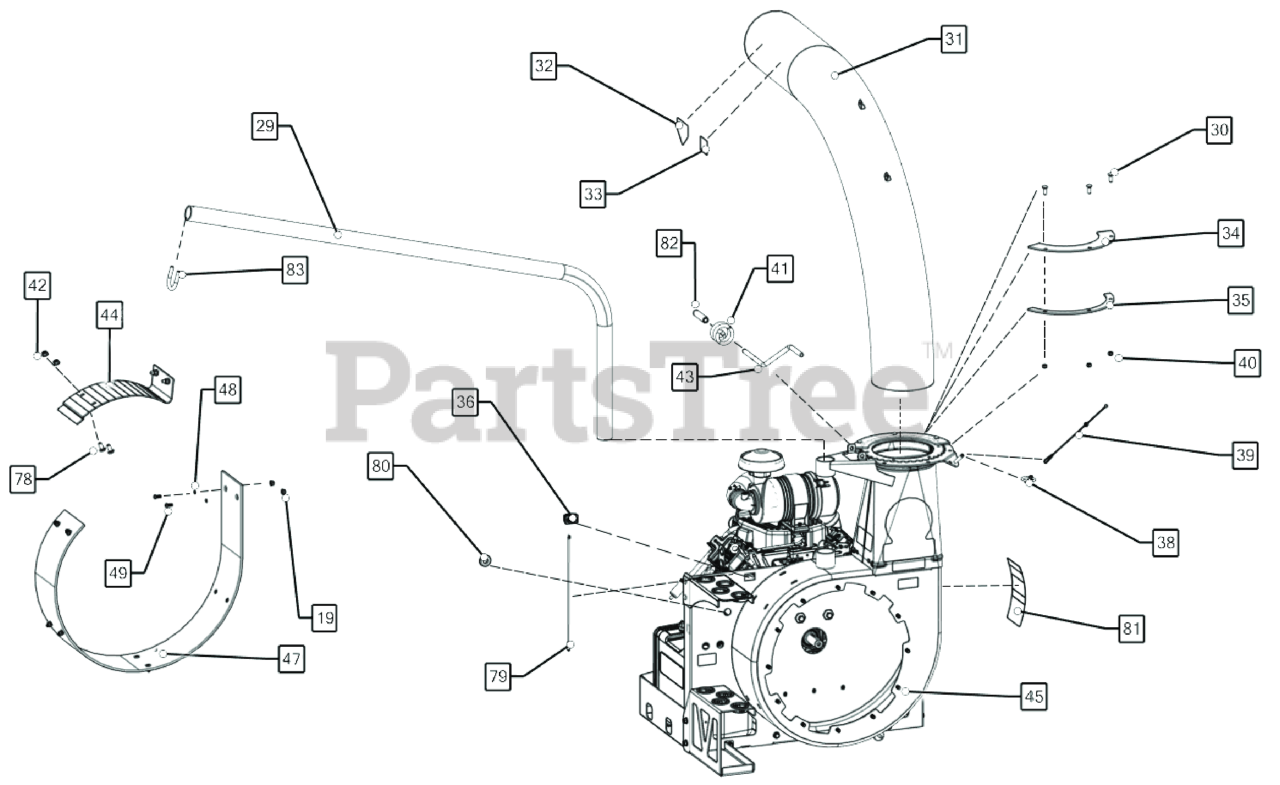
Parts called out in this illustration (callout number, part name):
19	NUT-HEX-NYLK, FLG .3125-18 ZP
29	BOOM HOSE
30	BOLT CARRIAGE 5/16"-18 X 3/4" ZP
31	ELBOW 8" DL SERVICE
32	LABEL WARNING OPEI
33	LABEL DANGER FLYING DEBRIS
34	PLATE CLAMP HALF DL
35	PLATE CLAMP SPLIT DL
36	HOURMETER, INDUCTIVE PANEL MOUNT
38	LYNCH PIN 3/16" X 1 9/16"
39	LANYARD PLASTIC 10"
40	NUT-HEX-NYLK, FLG .3125-18 ZP
41	GEAR WORM WELDED ASSEMBLY
42	NUT-HEX-NYLK, FLG .375"-16 ZP
43	SHAFT GEAR WORM
44	CUT OFF REPLACEABLE DL
45	HOUSING WA DL29/37
47	SEE: 791018-S
48	WASHER 5/16" SAE Z/P
49	SCREW BUTTON HEAD 5/16 X 0.75
78	BOLT CARRAIGE 3/8-16 X 1" ZP
79	WIRE, ASSY HOUR METER DL29/37
80	GROMMET 1" HOLE
81	LABEL QL INSTRUCTION/WARN
82	PIN ROLL 3/16 X 0.875 ZP
83	BOOM LOOP HOSE HANGER
